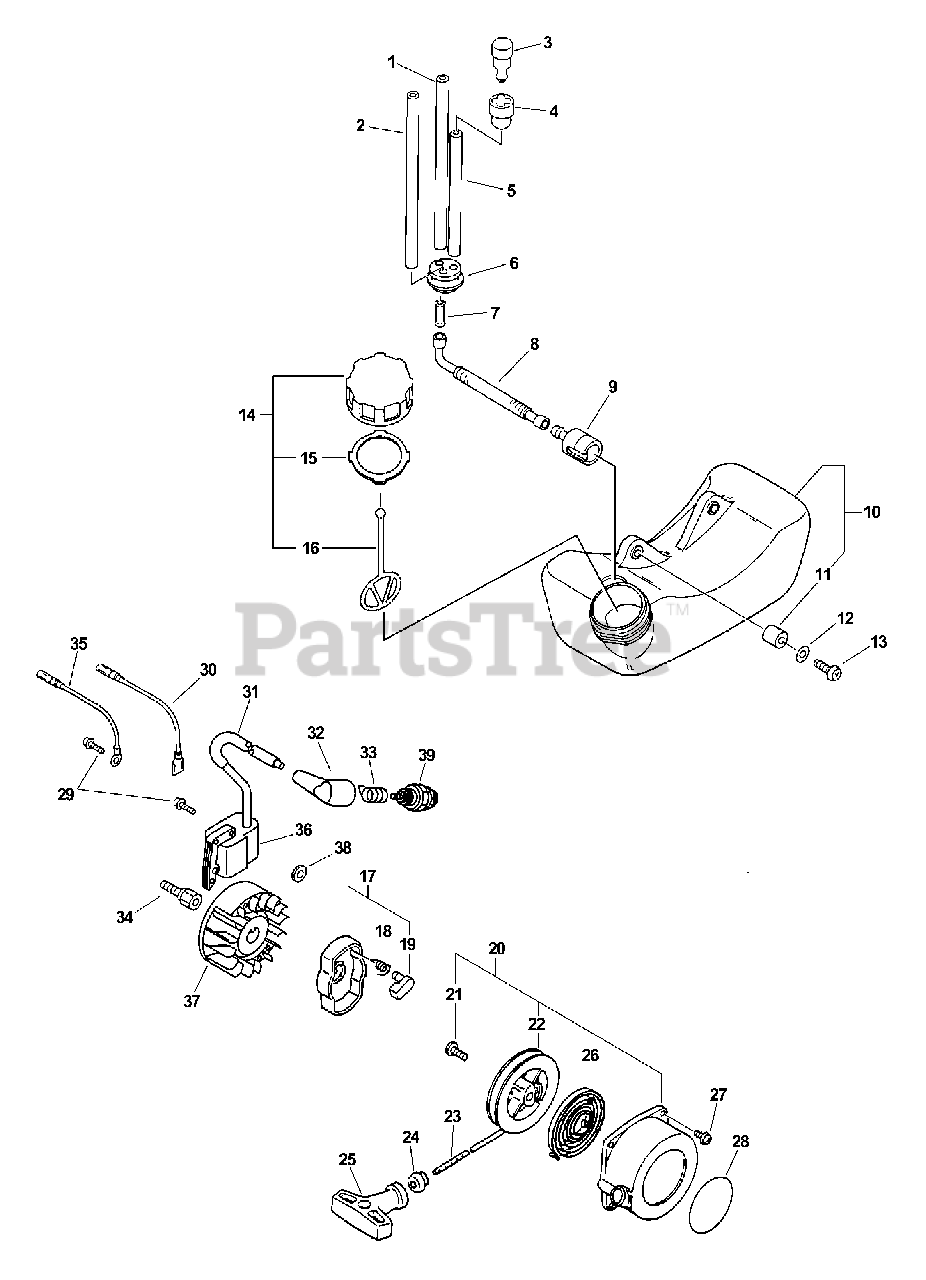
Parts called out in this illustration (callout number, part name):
1	PIPE, FUEL 3×5×90 BLACK
2	PIPE, FUEL RETURN 3×6×90 MM CLEAR
3	VENT ASSY
4	HOLDER, VENT
5	PIPE, FUEL 3x-5x-70 BLACK
6	GROMMET, FUEL
7	CONNECTOR, PIPE
8	PIPE, FUEL - CORRUGATED
9	FILTER, FUEL
10	TANK ASSY, FUEL
11	SPACER 6.2×7.8×6
12	WASHER 5.5×12×0.8
13	SCREW 5×16
14	CAP ASSY, FUEL
15	CONNECTOR, CAP L= 100 MM
16	CONNECTOR, CAP L= 100 MM
17	PAWL ASSY, STARTER
18	SPRING, RETURN
19	PAWL, STARTER - BLACK
20	STARTER ASSY, RECOIL
21	SCREW
22	REEL, ROPE
23	ROPE, STARTER 3.0×1000
24	GUIDE, ROPE
25	GRIP, STARTER
26	SPRING, RECOIL
27	BOLT 4×16
28	LABEL, ECHO
29	SCREW 4×22
30	LEAD - GROUND
32	CAP, SPARK PLUG
33	TERMINAL, SPARK PLUG
34	HUB, FAN
35	LEAD
35	LEAD - IGNITION
36	COIL, IGNITION
37	FLYWHEEL
38	COLLAR
39	SPARK PLUG - BPM-7Y
39	SPARK PLUG - BPMR7A
